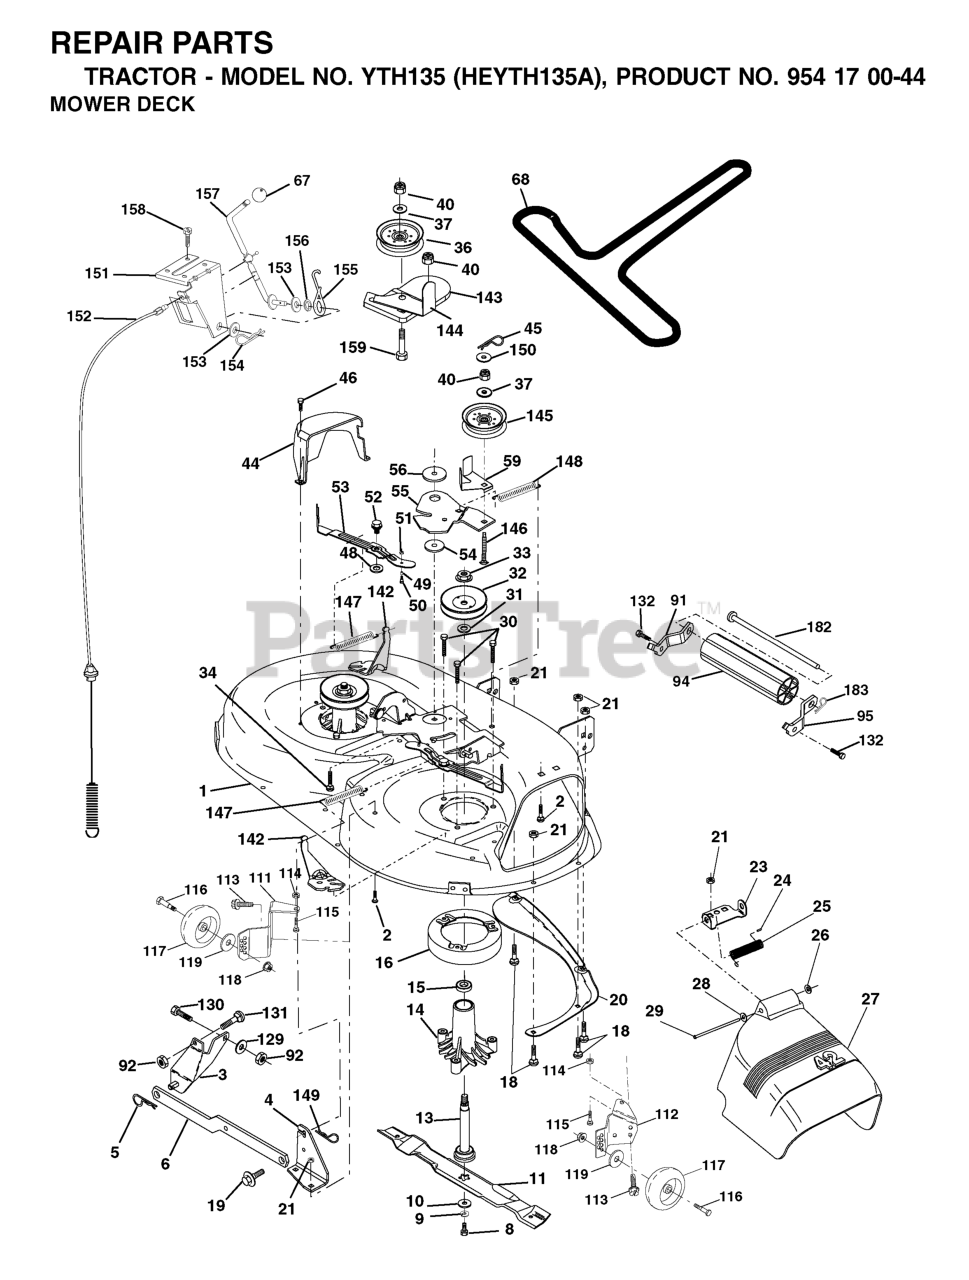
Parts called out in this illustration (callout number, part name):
1	42" DECK KIT
2	RP BOLT 5/16-18 X3/4 ZN/YEL GR
3	BRKT ASM SWAY BAR
4	BRACKET SWAY BAR 42" DECK
5	RETAINER-SPRNG RB
6	BAR SWAY DECK
8	BLADE BOLT
9	LOCKWASHER
10	WASHER.BLADE
11	Blade Mower 42" High Perf.
13	SHAFT ASM VENT
14	HOUSING.MANDREL.VENTED (MACHD)
16	STRIPPER.MANDREL.ROUND.BLACK
18	BOLT
19	BOLT SHD 5/16-18
20	BAFFLE.VORTEX
21	LOCKNUT
23	BRKT, DEFL. MOWER
24	CAP-SLEEVE LT
25	SPRING TORSION
26	NUT PUSH M
27	SHIELD DEFLECTOR
28	Washer 11/32 x 5/8 x 16 Ga SD
29	ROD.HINGE
30	SCREW, WASHER HEAD
31	WASHER
32	PULLEY/MANDREL
33	NUT, FLG TOPLOCK 9/16"
36	FLAT IDLER PULLEY
37	WASHER
44	GUARD MANDREL LH BLACK
45	RETAINER M
46	SCREW.1/4-20X5/8
49	ROLLER ASM CAM FOLLOWER
52	BOLT.SHOULDER.5/16-18
53	ARM
54	HARDENED WASHER
55	ARM IDLER 42" MOWER LT/YT
56	SPACER.RETAINER.MOWER
59	GUARD, BELT
67	KNOB T (3/8 HOLE)
91	BRACKET ASM NOSEROLLER LH
92	NUT
94	NOSE ROLLER
95	BRACKET ASM NOSEROLLER RH
111	BRACKET, WHEEL
112	BRACKET, WHEEL
113	Screw Tapping 3/8-16 x .625
114	NUT
115	BOLT.CARR.5/16-18X5/8.SHORT
116	BOLT M
117	WHEEL.GAUGE.STANDARD
118	LOCKNUT
119	WASHER.5/16.FLAT.STE.STD.
129	WASHER
131	BOLT D
132	SCREW 3/8-16X3/4
142	ARM SPRING BRAKE MOWER
143	BRACKET, ARM IDLER
144	DNO KEEPER.BELT.42".CLUTCH.CBL
145	PULLEY
146	BOLT, CARRIAGE IDLER BLACK
148	IDLER RETURN SPRING
149	SPRING.RETAINER.YELLOW.ZINC
151	BRACKET.CLUTCH.CABLE
152	CABLE.CLUTCH.42"
153	WASHER FLAT 3/8"
154	SPRING RETAINER
155	SPRING RETENTION LEVER
156	SPACER.CLUTCH.CABLE
157	ROD CLUTCH CABLE 3/8"
158	SCREW
182	ROD ROLLER NOSE STANDARD
183	SPRING RETAINER
